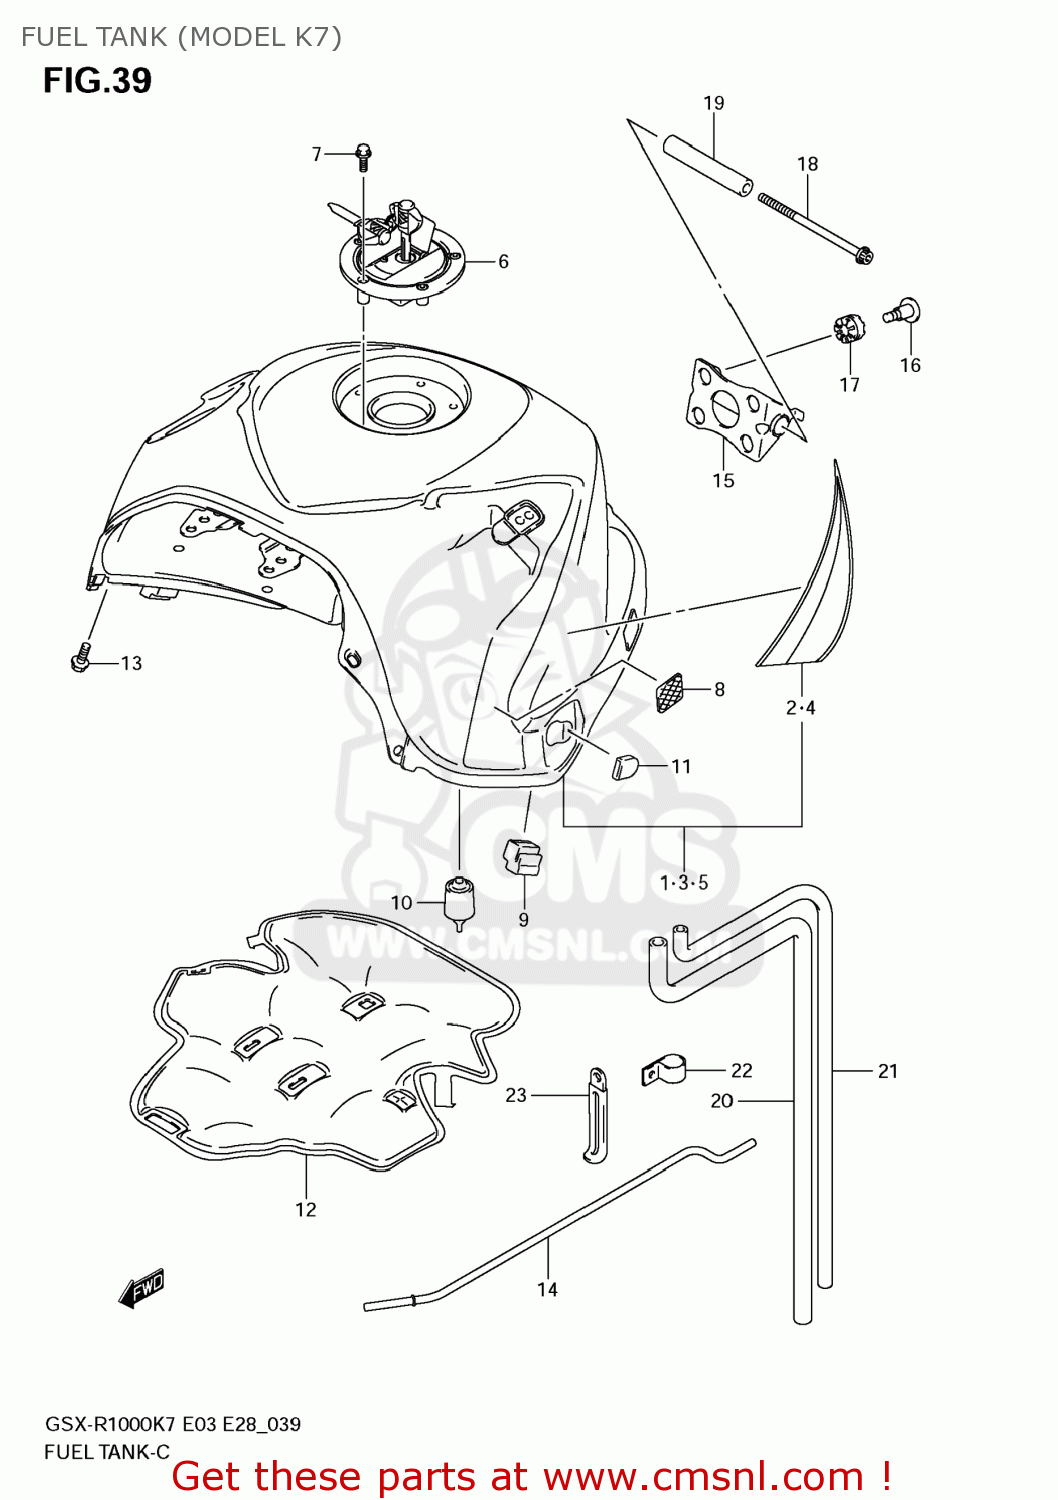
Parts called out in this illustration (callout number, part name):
1	TANK ASSY,FUEL(BLUE)
2	TAPE SET,FUEL TANK
3	TANK ASSY,FUEL(YELLOW)
4	TAPE SET,FUEL TANK
5	TANK ASSY,FUEL(BLACK)
6	CAP SET,FUEL TANK
7	BOLT(5X20)
8	FASTENER
9	CUSHION,FUEL TANK SIDE
10	CUSHION,FUEL TANK RR
11	CUSHION
12	SHIELD,FUEL TANK HEAT
13	SCREW(6X10)
14	STAY,FUEL TANK
15	BRACKET,FUEL TANK NO.1
16	SCREW,FUEL TAN
17	CUSHION
18	BOLT(6X110)
19	SPACER,FUEL TANK RR
20	HOSE,FUEL TANK WATER DRAIN
21	HOSE,FUEL TANK BREATHER
22	CLAMP
23	CLAMP(L:80)
